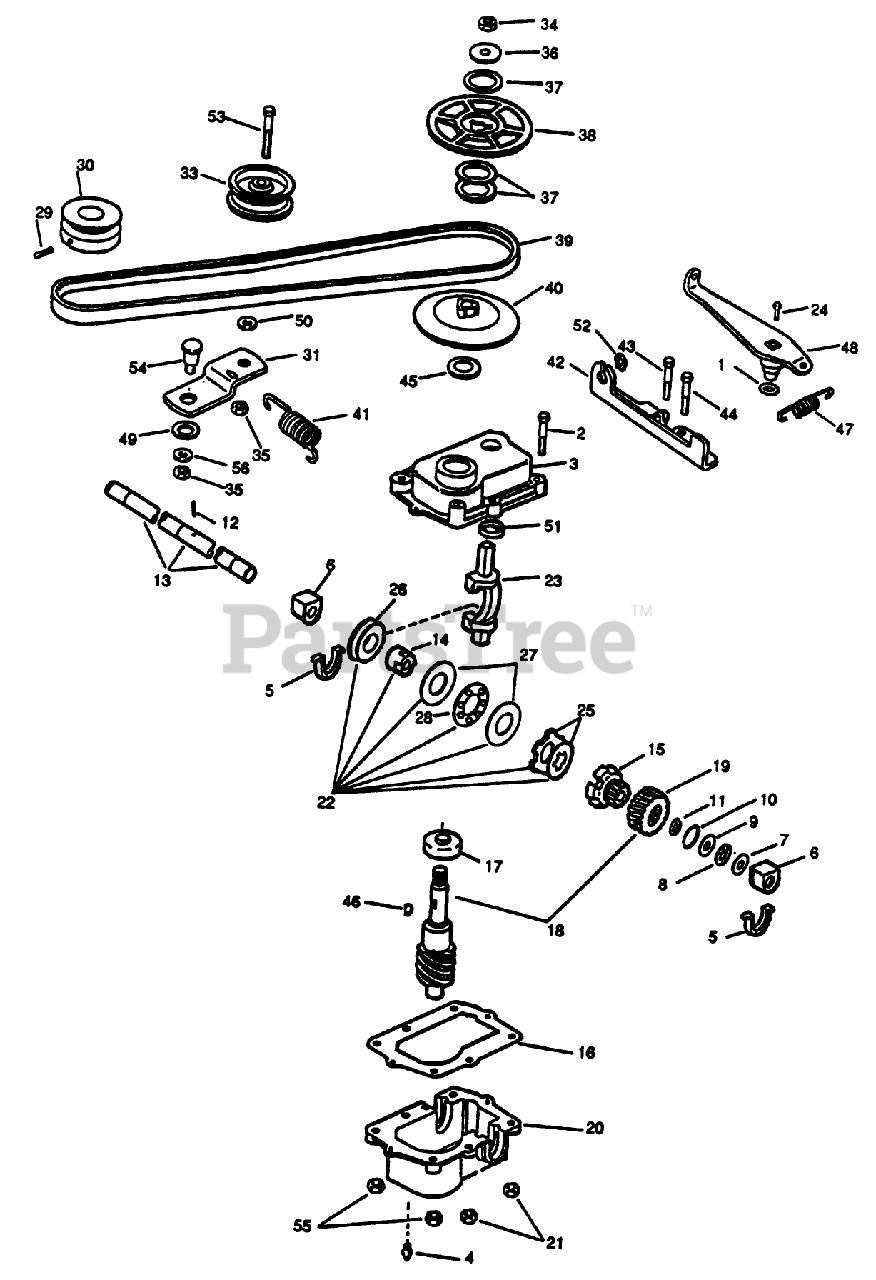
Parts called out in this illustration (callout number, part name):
1	O-RING
4	Plug
6	BEARING & SEAL AY (12)
7	THRUST WASHER
9	WASHER-THRUST
11	RET RING
12	PIN DRIVE LOCK
13	SHAFT - DRIVE
15	DRIVER BROCKWAY
16	GASKET HOOSIER
17	BEARING-BALL
19	WORM WHEEL
21	LOCKNUT E
23	FORK SHIFT
24	SCREW SEMS SM
25	Disc Plate Kit
26	Collar
29	SET SCREW F
30	PULLEY F
33	PULLEY IDLER NHI
34	NUT-JAM, LOCKING
35	LOCKNUT
36	WASHER
38	PULLEY UPPER PL
39	V-BELT F
40	PULLEY LOWER PL
41	SPRING-EXT.
45	WASHER
46	KEY GALGER
47	SPRING
50	WASHER S
51	GUIDE ELCO
52	RET. RING
55	LOCKNUT E
56	WASHER
